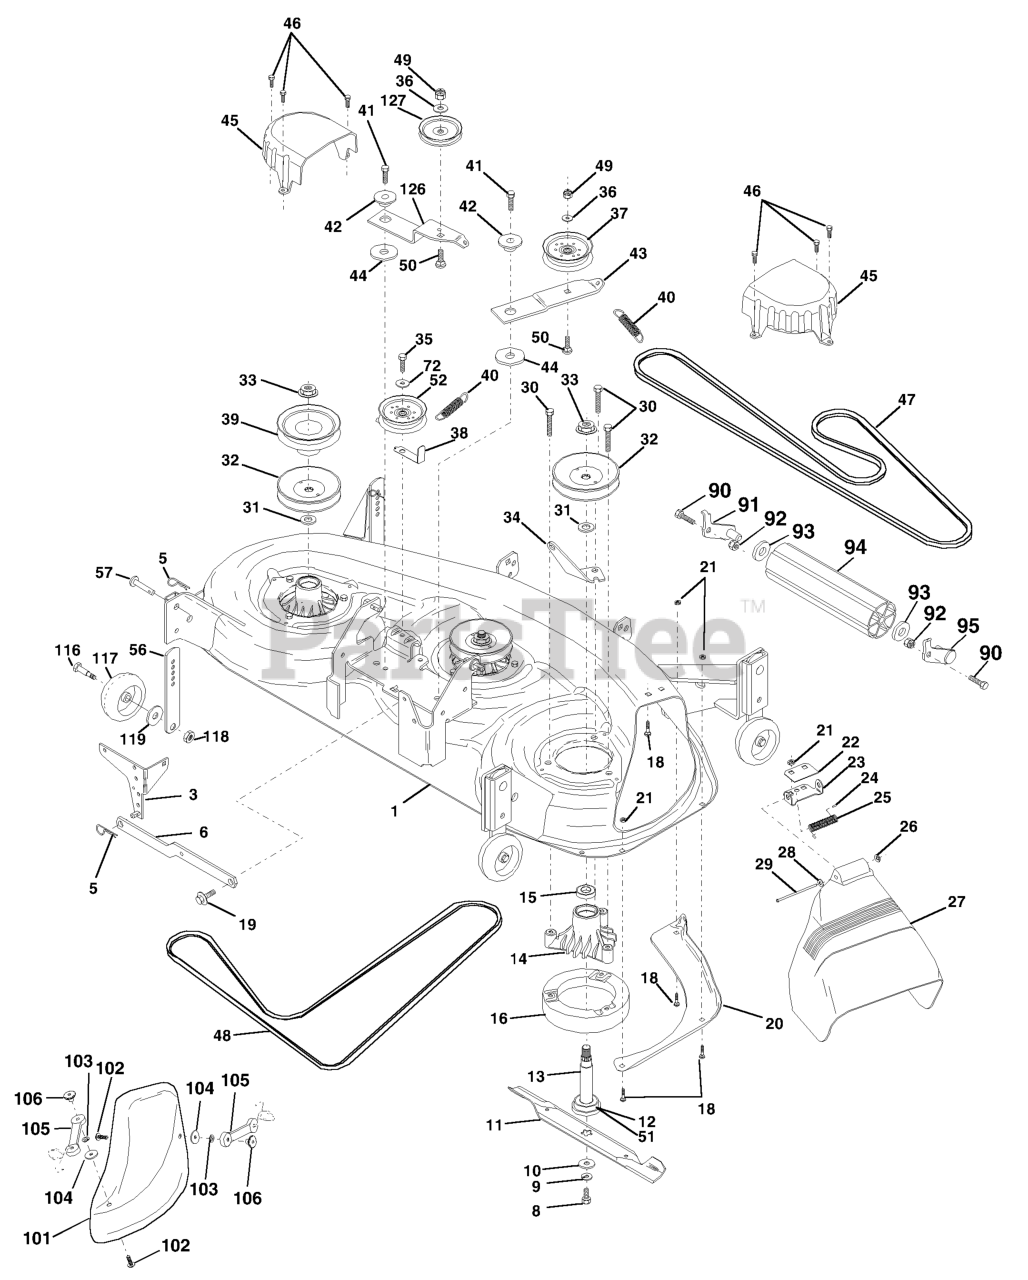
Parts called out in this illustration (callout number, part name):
1	DECK
3	BRACKET SWAY BAR
5	RETAINER-SPRNG RB
6	REAR SUSP ARM
8	BLADE BOLT
9	LOCKWASHER
10	WASHER.BLADE
11	MULCH BLADE
12	BEARING.BALL.#6204.(MANDREL)
13	SHAFT.ASM.W/BEARING
14	HOUSING.MANDREL.44/46" VENT
16	STRIPPER
18	BOLT
19	BOLT SHD 5/16-18
20	BAFFLE, VORTEX MOWER 46"
21	LOCKNUT
22	STIFFENER BRACKET
23	DEFLECTOR BRACKET
24	CAP-SLEEVE LT
25	TORSION SPRING
26	NUT PUSH M
27	DEFLECTOR SHIELD
28	Washer 11/32 x 5/8 x 16 Ga.
29	ROD.HINGE
30	SCREW THDROL ROLLING WASHER HD
31	WASHER
32	PULLEY, MANDREL
33	NUT
34	ANCHOR, SPRING DECK 46"
35	SCREW LT
36	WASHER
37	FLAT IDLER PULLEY
38	KEEPER.BELT.IDLER
39	PULLEY.DRIVEN.DECK.46"
40	SPRING.SEC.44"VEN
41	SCREW
42	SPACER RETAINER
43	ARM IDLER DECK 46"
44	HARDENED WASHER
45	COVER MANDREL 46
46	SCREW.1/4-20X5/8
47	BELT V SECONDARY
48	V-BELT PRIMARY 50"
50	BOLT.3/8-16X1.50
51	WASHER FELT
52	PULLEY IDLER FLAT 46 PRI DRIVE
56	BAR.ADJUST.WHEEL.ANTI.SCALP.BL
57	RIVET.PIN.HEAD.YELLOW.
72	WASHER
90	BOLT
91	BRACKET LH (A)
92	NUT
93	Washer 17/32 x 7/8 x 16 Ga.
94	NOSE ROLLER
95	BRACKET RH (B)
101	COVER.MULCH.46"3-BLADE.(2 2)
102	SCREW
103	LOCKWASHER #10
104	WELDNUT
106	LATCH ASSY
116	BOLT, SHOULDER
117	WHEEL GAGE DONUT
118	LOCKNUT
119	WASHER.5/16.FLAT.STE.STD.
126	ARM IDLER PRIM 46
127	PULLEY.IDLER.4.25
